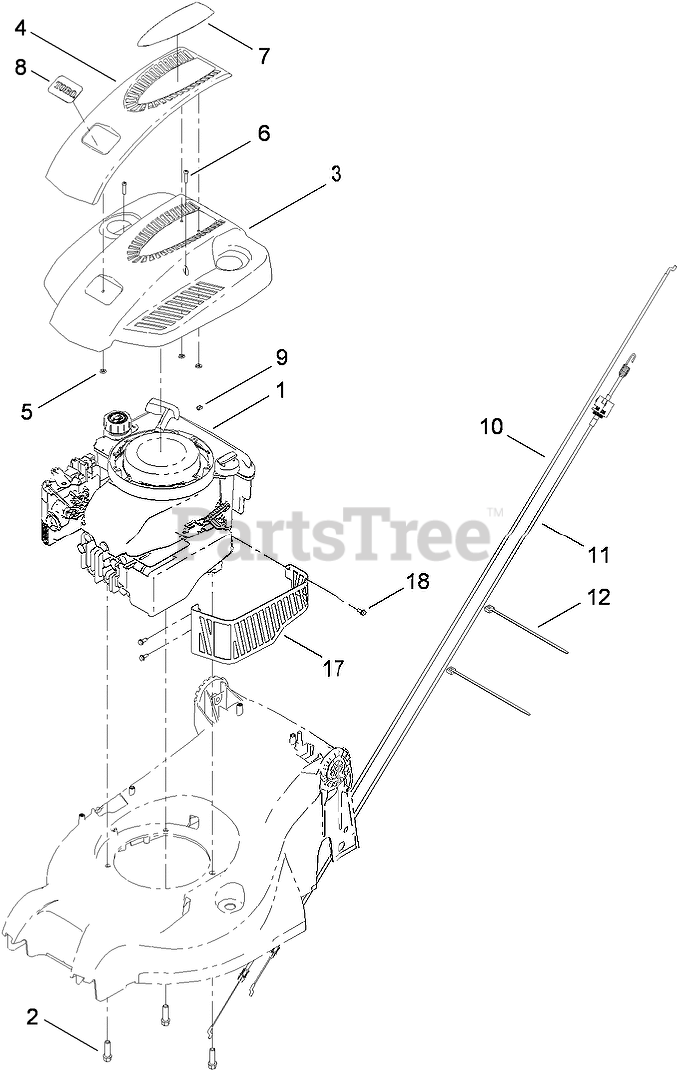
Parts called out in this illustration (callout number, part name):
2	SCREW-TAPTITE
3	SHROUD-ENGINE
4	COVER-SHROUD
5	CLIP-PUSH
6	SCREW-PPH
9	STOP-ROPE
10	CABLE-BRAKE
11	CABLE-TRACTION
12	TIE-CABLE
17	SHIELD-MUFFLER
18	SCREW-TAPTITE
